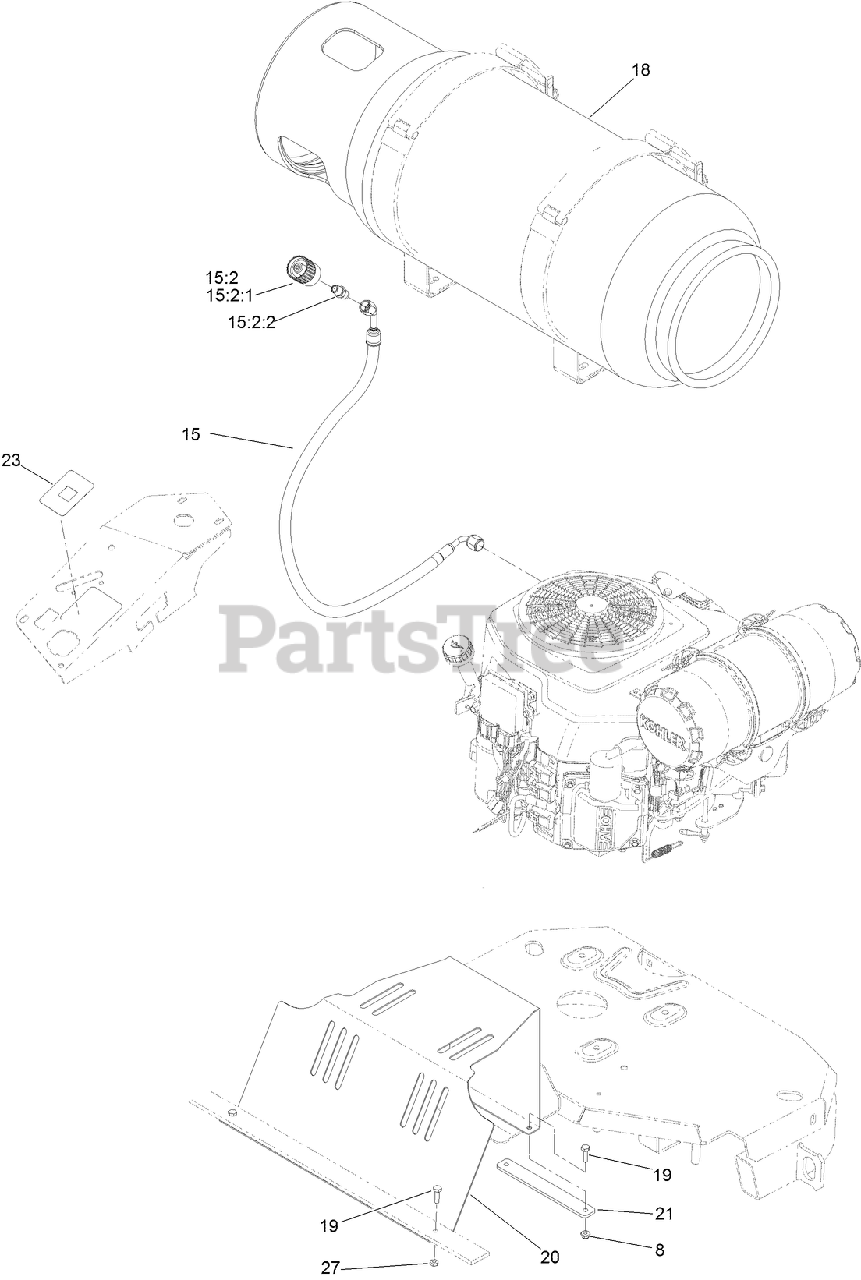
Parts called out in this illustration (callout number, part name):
8	NUT-HF
15	LPG HOSE ASM
15:2	CONNECTOR-LP, STRAIGHT
15:2:1	CONNECTOR-LPG TANK, LH THREAD
15:2:2	FITTING-STR
18	TANK-LPG
19	SCREW-HH
20	SHEILD-FAN
23	DECAL-METER, HOUR
27	NUT-JAM
